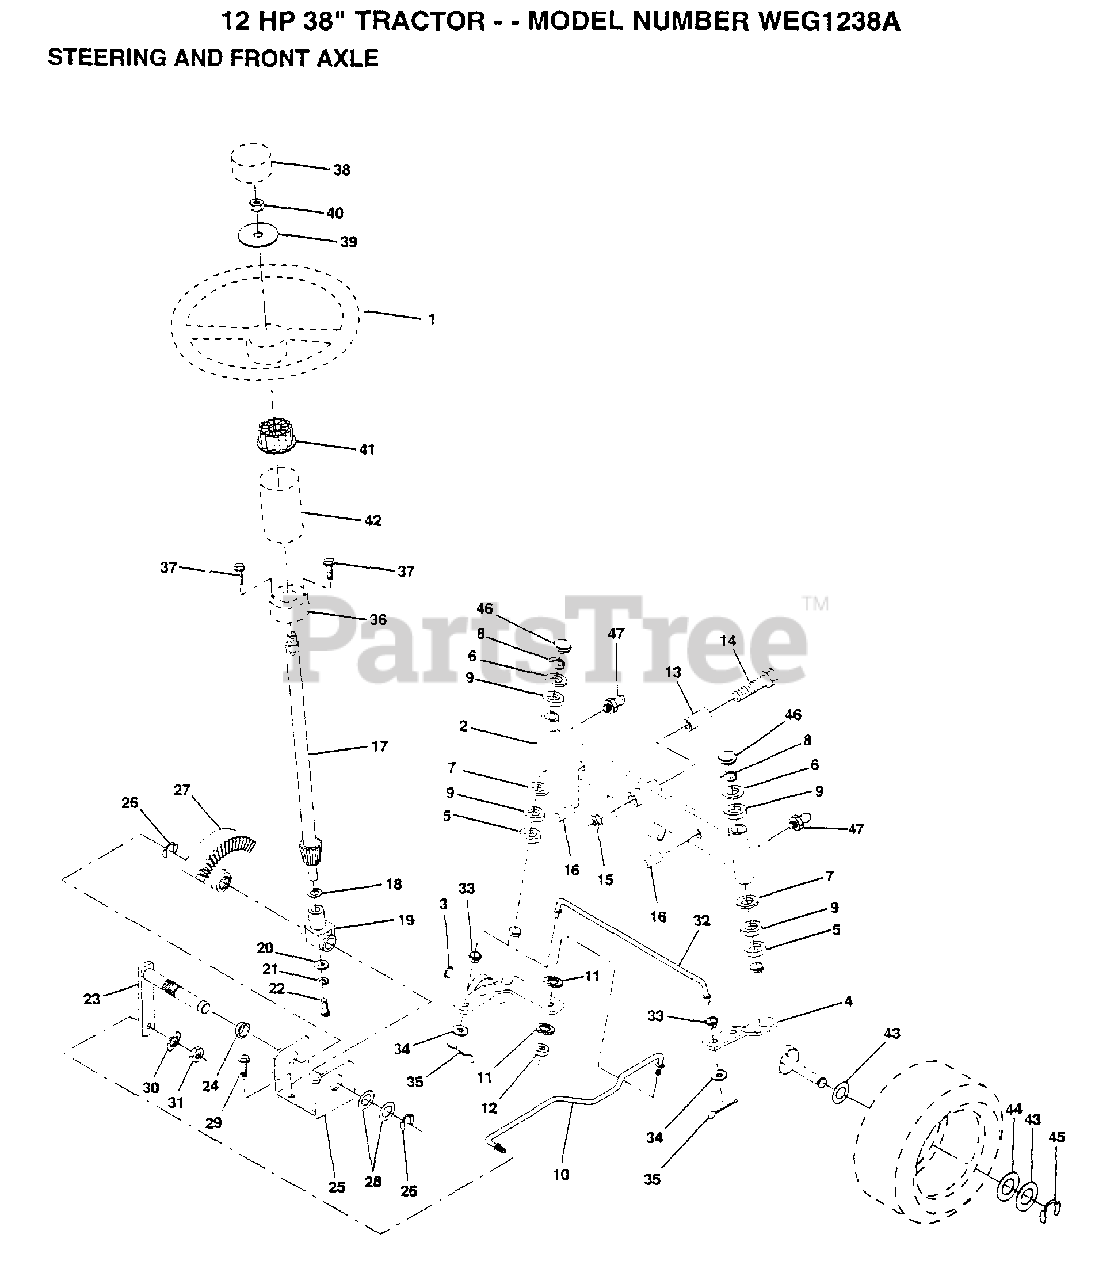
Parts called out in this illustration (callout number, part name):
2	AXLE ASM FRONT
3	SPINDLE LH
4	SPINDLE RH
5	WASHER .T
6	WASHER
7	WASHER
8	RING
9	COL. SRTG. BEAR.
11	LOCKWASHER
13	BEARING
14	BOLT HEX 5/8-11
15	"NUT-LOC,FLANGE LT"
16	AXLE PIN
17	SHAFT ASM
18	THRUST WASHER
19	SUPPORT.SHAFT
21	LOCKWASHER
22	"SCREW,SPECIAL"
24	NYLINER T
25	"BRKT,STEERING"
26	RING
27	GEAR SECTOR
28	WASHER .T
29	SCREW
30	LOCKWASHER
32	TIE ROD
33	BUSHING.DRAGLINK
34	WASHER
35	COTTER PIN
38	ST WHL INSERT CAP
39	WASHER T
40	GRIPCO NUT
41	ADAPTER-WHEEL LT
42	"TUBE, STR SHAFT"
43	WASHER
44	WASHER
45	RING
46	CAP
47	ZERK M
